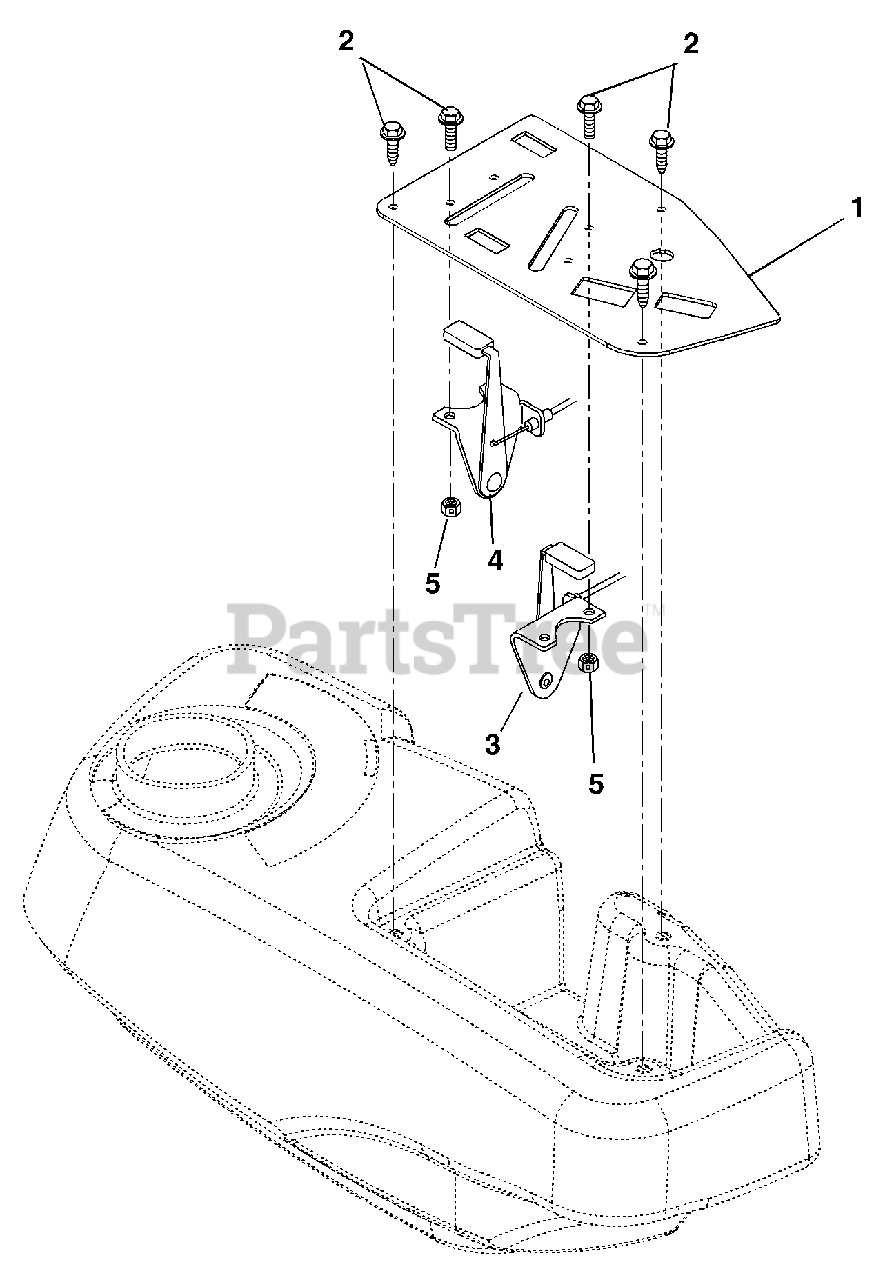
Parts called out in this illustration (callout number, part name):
1	Panel-Control
2	Screw-Machine 10-24 x .50 Hex Washer Head
3	Throttle Control
4	Choke Control (029, 030, 034, 035)
4	Choke-Control (020)
5	Nut-Locking-Nylon 10-24 With Insert
